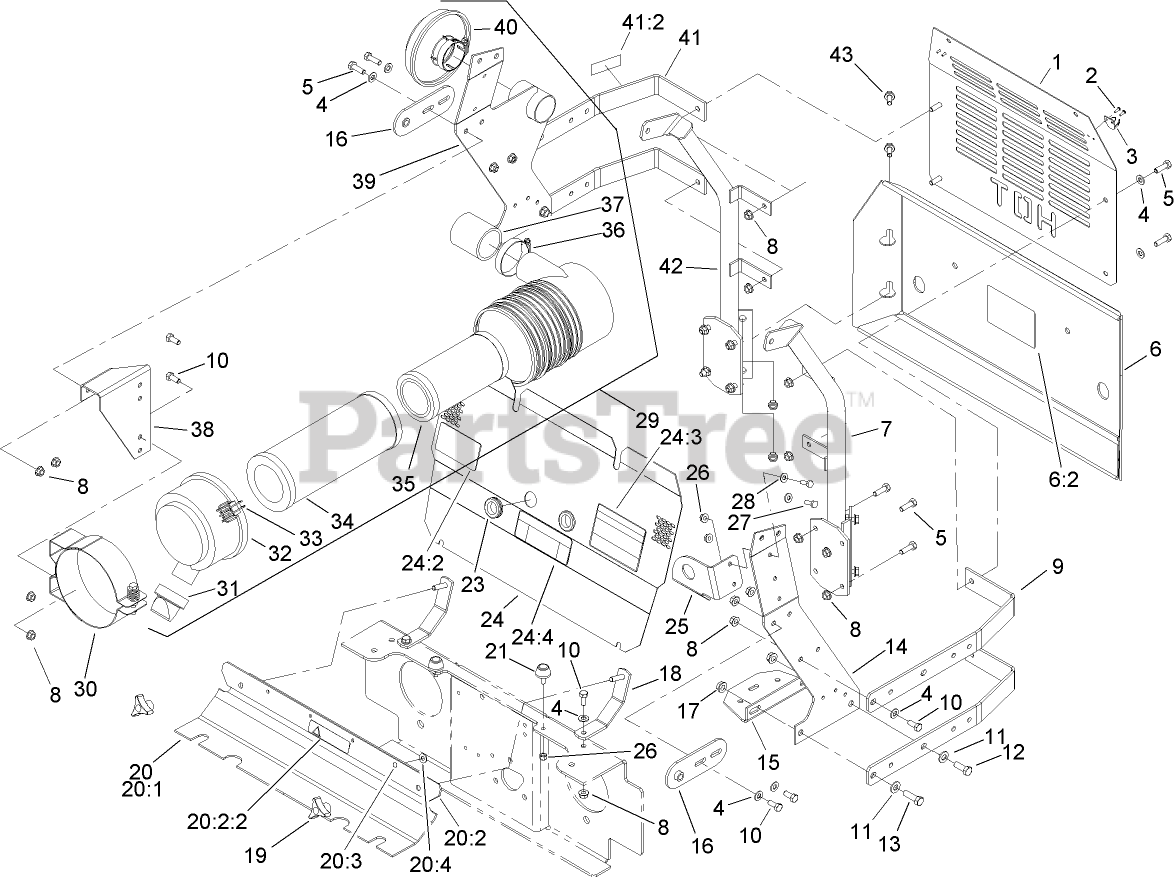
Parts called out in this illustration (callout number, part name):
1	GUARD-MUFFLER
2	RIVET
3	KEEPER-LATCH, RUBBER
4	WASHER-PLAIN
5	SCREW-HH
6	REAR BUMPER ASM
6:2	DECAL-BELT ROUTING, DECK DRIVE
7	FRAME-UPPER, LH REAR
8	NUT-HF
9	BAR-MOUNT FRAME, RADIATOR
10	SCREW-HH
11	WASHER-FLAT
12	SCREW-HH
13	SCREW-HH
14	MOUNT-SIDE, LH
15	BRACKET-BOTTLE
16	SHACKLE-HINGE
17	NUT-HHF, WHIZ
18	MOUNT-BELT SHIELD, ENGINE
19	KNOB-3 PRONG
20	ENGINE BELT SHIELD ASM
20:1	SHIELD-ENGINE
20:2	STRIP-SHIELD, BELT
20:2:2	DECAL-COVER, MISSING
20:3	RIVET-POP
20:4	WASHER-FLAT
21	BUMPER
23	GROMMET-RUBBER
24	ENGINE ACCESS PANEL ASM
24:2	DECAL-BELT ROUTING, PUMP
24:3	DECAL-BUZZER, WARNING
24:4	DECAL-DEVICES, ROTATING
25	BRACKET-BUZZER
26	NUT-HF
27	SCREW-HH
28	WASHER-FLAT
29	FILTER-AIR
30	BRACKET-FILTER, AIR
31	VALVE-VACUATOR
32	COVER-FILTER, AIR
33	LATCH-CLEANER, AIR
34	FILTER-AIR
35	FILTER-AIR, SAFETY
36	CLAMP-HOSE
37	HOSE-INTAKE
38	MOUNT-CLEANER, AIR
39	RH RADIATOR AND AC SUPPORT ASM
40	HOOD-CLEANER, 2" AIR INTAKE
41	BAR-RADIATOR
41:2	DECAL-SURFACE, HOT
42	FRAME-UPPER, RH REAR
43	SCREW-HHF
